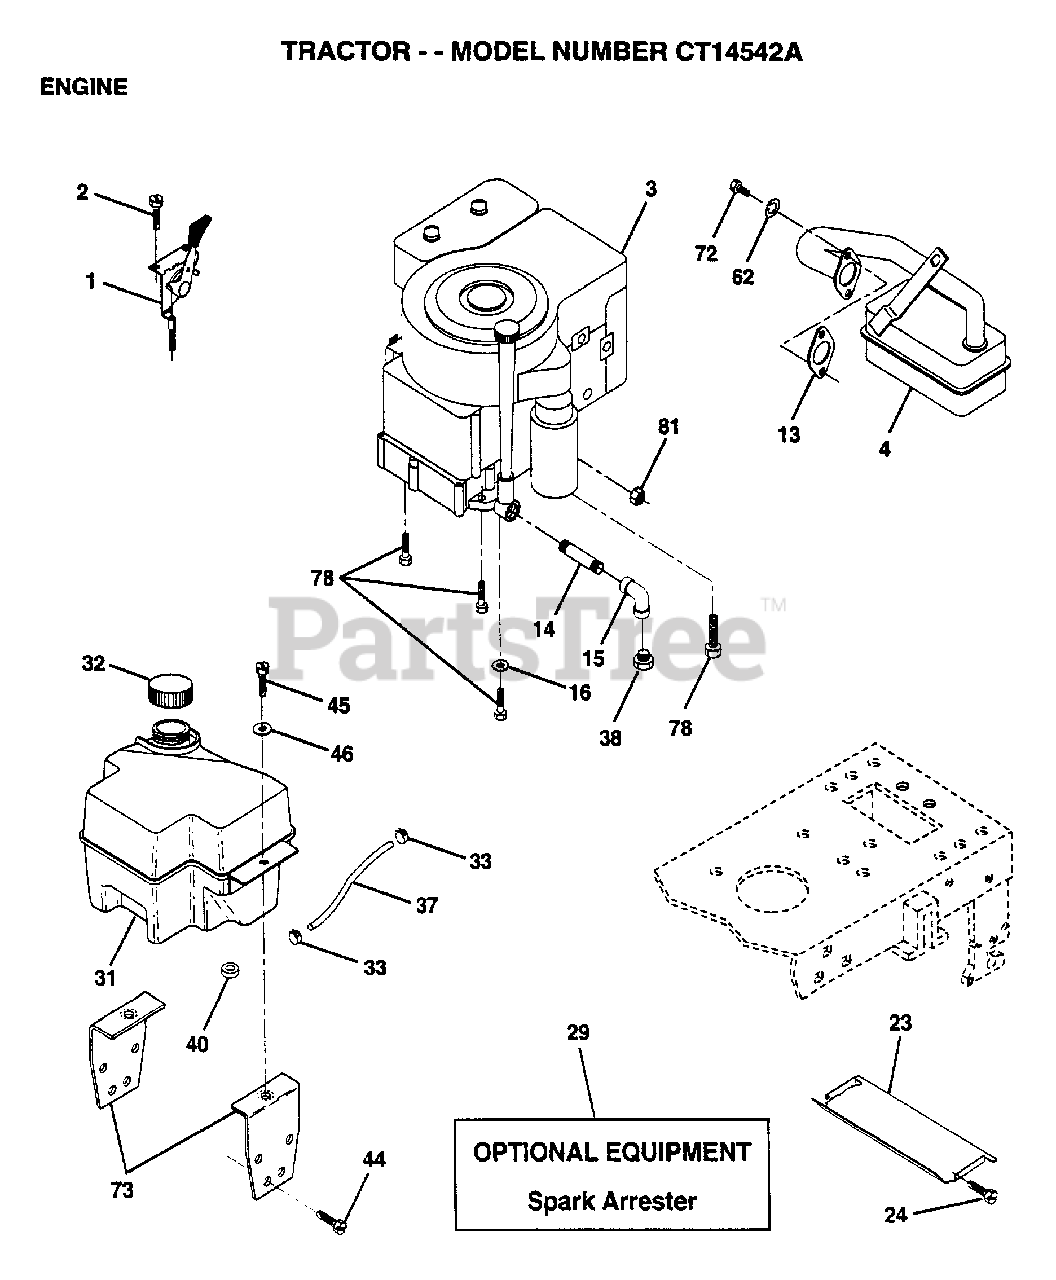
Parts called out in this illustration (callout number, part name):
1	CONTROL.THTL.19.6
2	SCREW LT
4	MUFFLER
14	PIPE NIPPLE
15	ELBOW
16	LOCKWASHER
23	HEAT SHIELD
32	CAP ASM FUEL
33	HOSE CLAMP
37	LINE FUEL
45	SCREW HEX CRT
46	WASHER
49	SCREW
62	LOCKWASHER
72	SCREW
73	BRACKET.SUPT.TANK
78	SCREW
81	NUT
